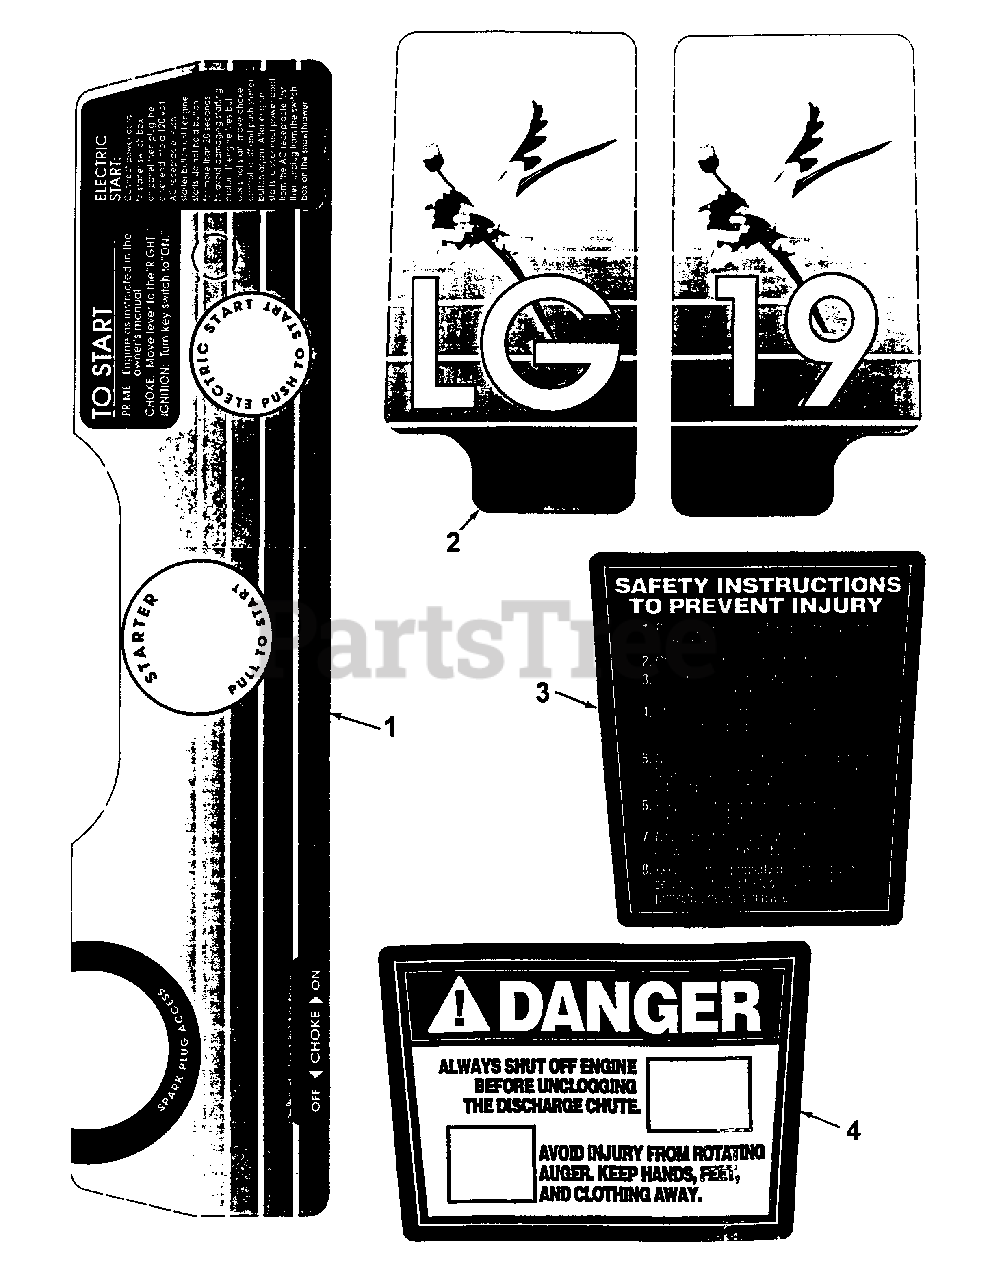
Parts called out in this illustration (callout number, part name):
1	DECAL, Panel/Instructions- Electric Start
2	DECAL, Model/I.D.
3	DECAL, Safety Instruction
4	DECAL, Danger, Chute/Deflector
